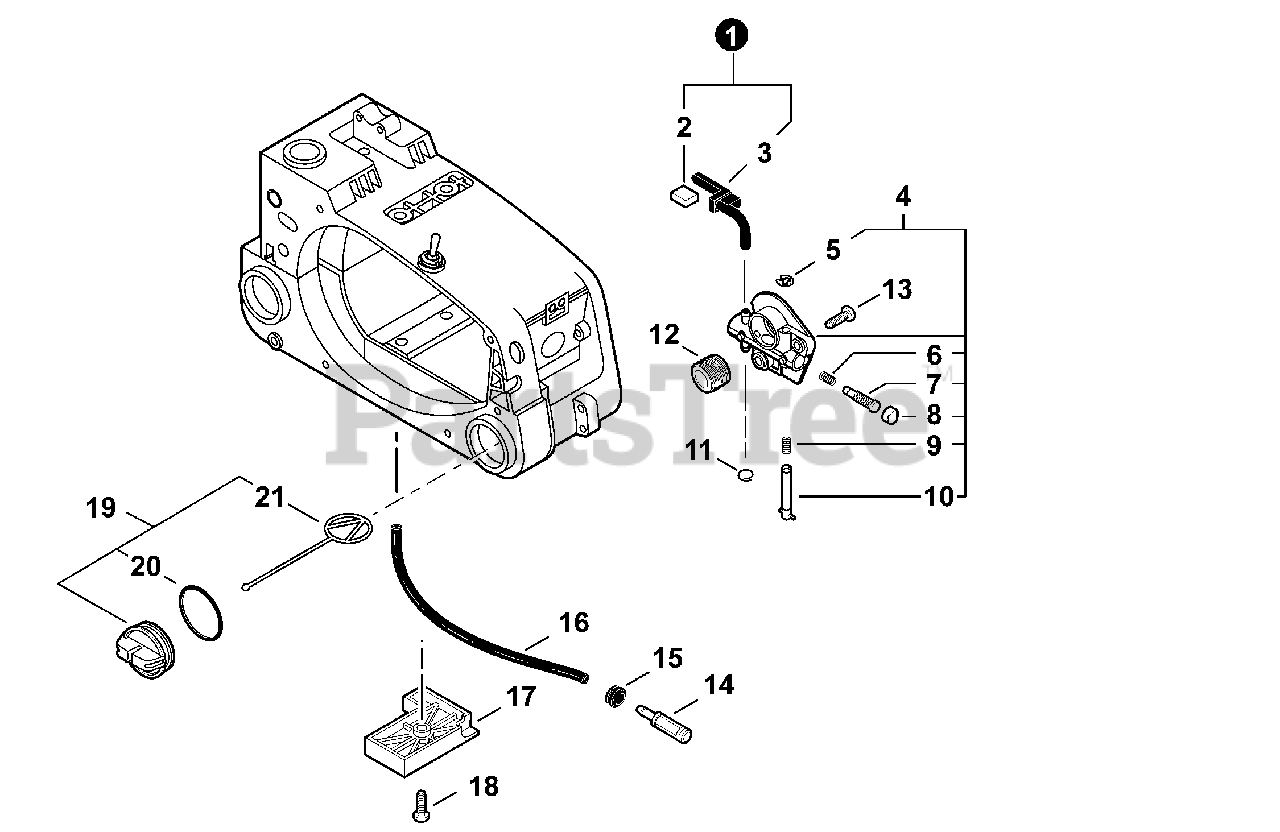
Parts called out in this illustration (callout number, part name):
1	PIPE KIT, OIL
2	PAD, FOAM
3	PIPE, OIL OUTLET
4	AUTO-OILER ASSY
7	PLUNGER ASSY
8	CAP, PLUNGER
10	ADJUSTER, OILER
11	CLIP 6.5 MM
12	GEAR, WORM
13	SCREW 5x12
14	FILTER, OIL
16	PIPE 3x6x115 BLACK
17	COVER, BOTTOM
18	SCREW 4x16
19	CAP ASSY
20	O-RING 25
21	CONNECTOR, CAP L= 60 MM
